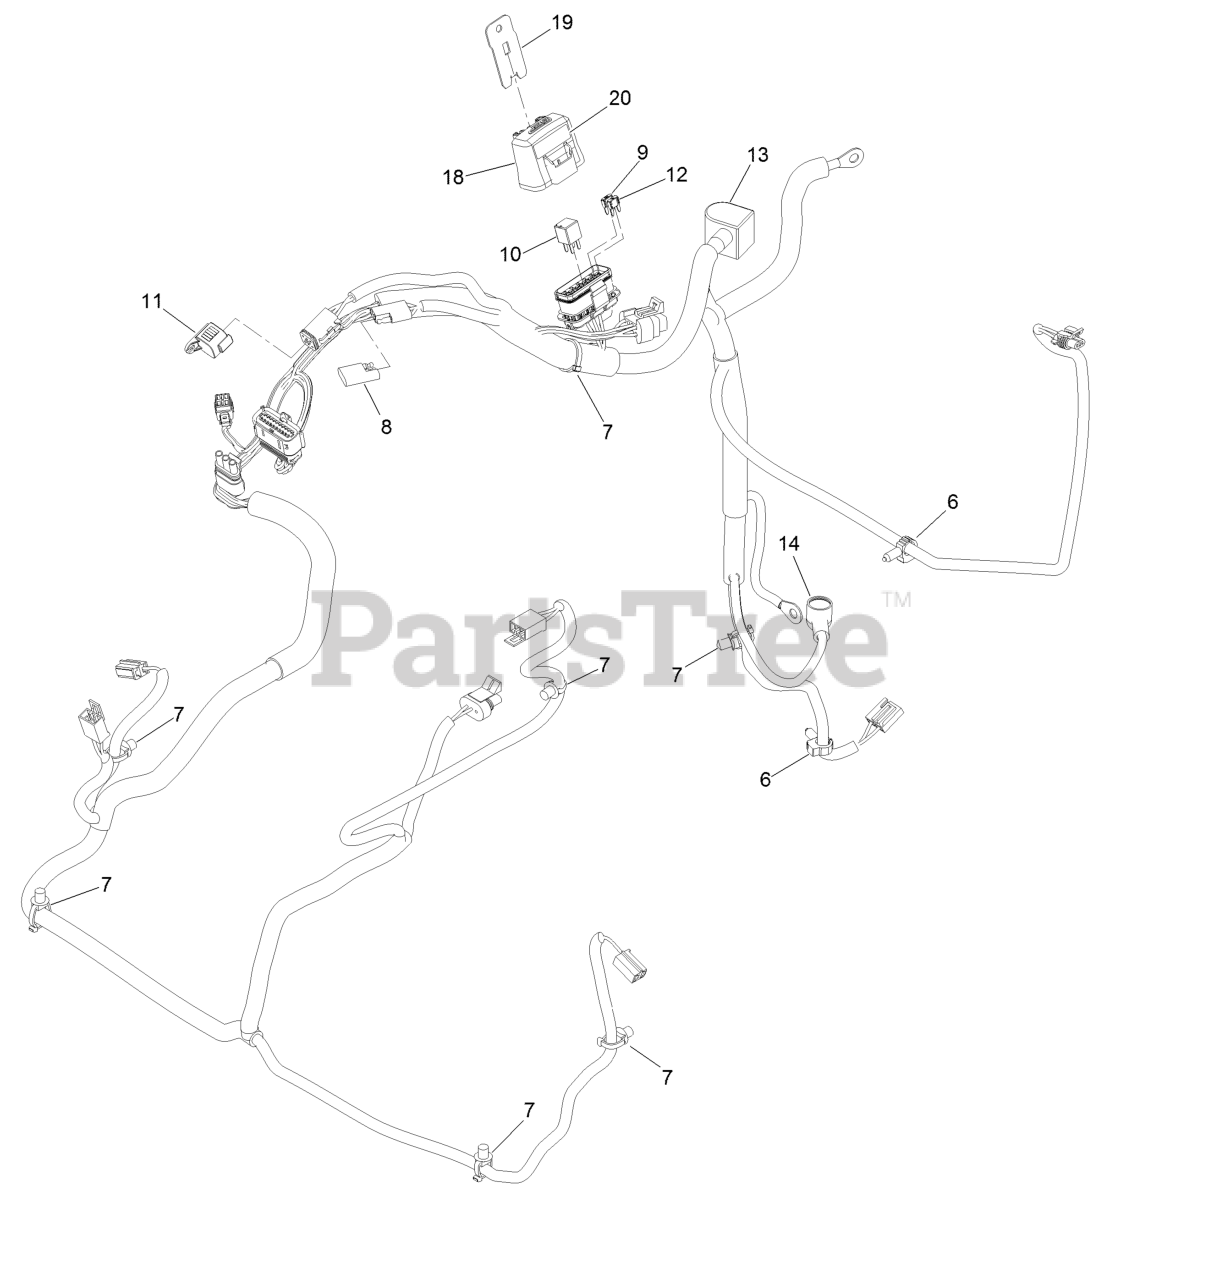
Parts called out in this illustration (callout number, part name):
6	Clip-Harness
7	Clip-Tie
8	Cap-Plug
9	Fuse-Mini Blade, 20 Amp
10	Relay-Micro
11	Cap-Plug, 6 Way
12	Fuse-Mini Blade, 15 Amp
13	Insulator-Battery
14	Insulator-Solenoid
18	Cover-Block, Fuse
19	Clip-Mounting
20	Decal-Fuse
